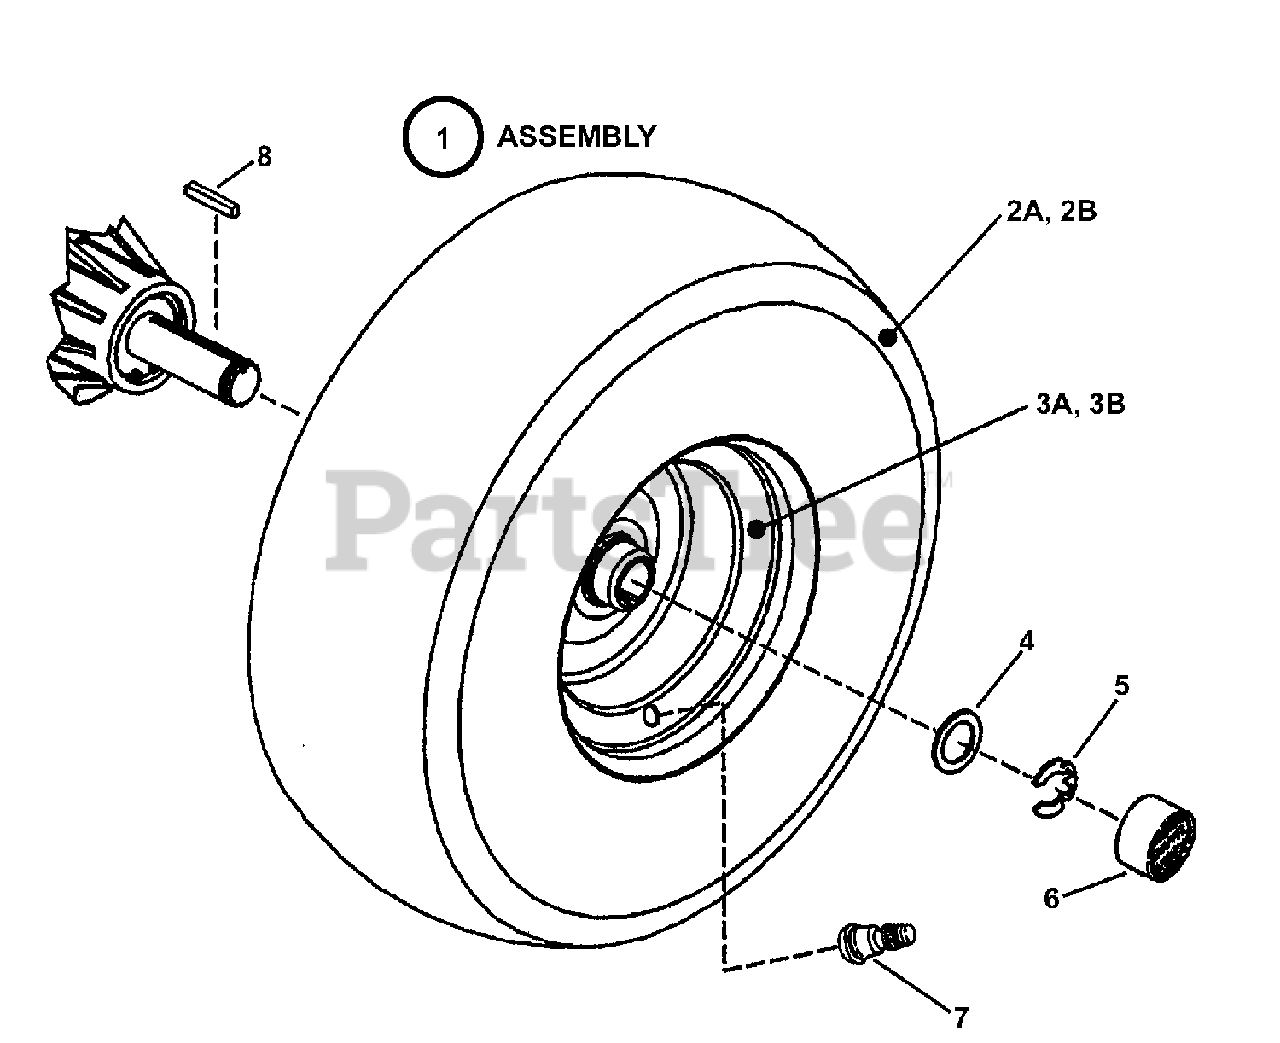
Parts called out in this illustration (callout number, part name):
1	ASSEMBLY, Rear Tire & Rim (Includes items 2A, 3A & 7)
2A	TIRE, 18 x 7.00-8, Multi-Trac (33" Models)
2B	TIRE, 18 x 8.50-8, Multi-Trac (38" Models)
3A	RIM, 18 x 7.00 Wheel w/25mm Hub I. D.
3B	RIM, 18 x 8.50 Wheel w/25mm Hub I. D.
4	WASHER, 1.56 x 1.054 x .047 Flat
5	KLIPRING, 1" External (Waldes Truarc 5304-100)
6	CAP, Hub
7	AIR VALVE STEM & CAP, Snap-In
8	KEY, Square M6 x 38mm
